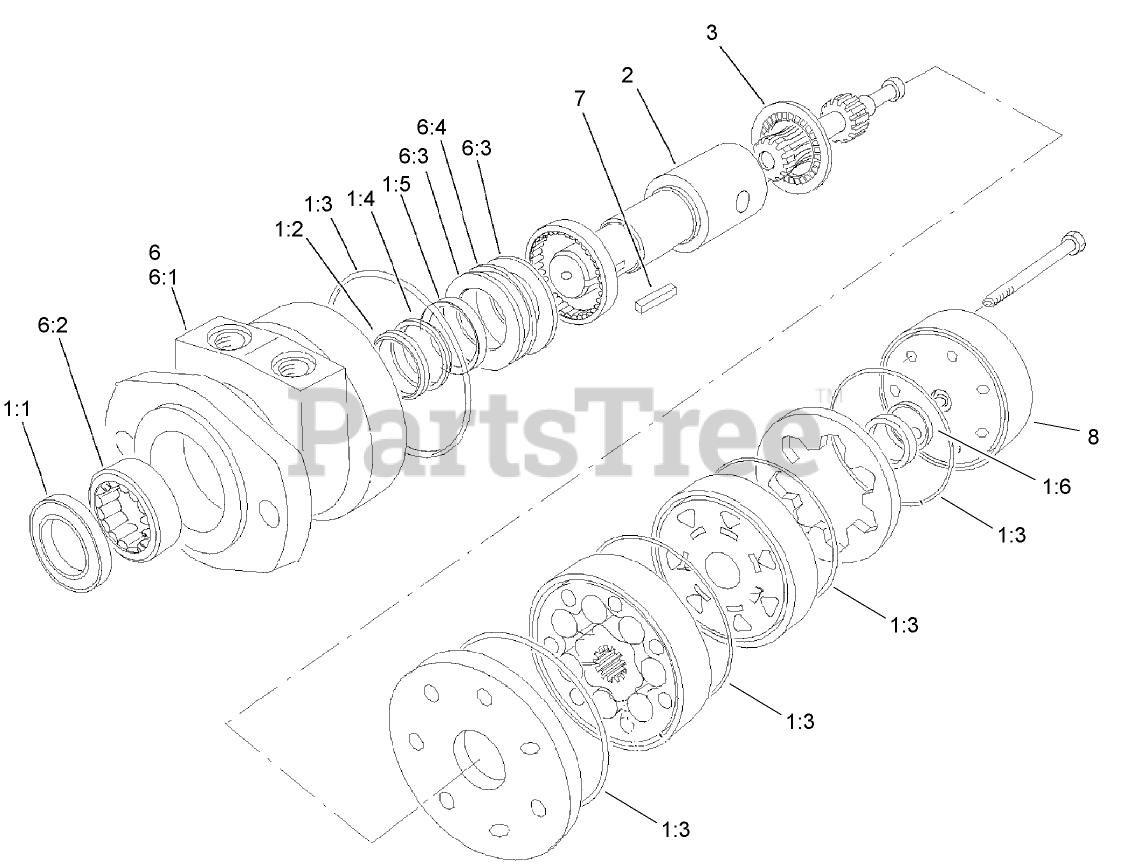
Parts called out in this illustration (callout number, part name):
1	SEAL KIT
1:1	SEAL-DIRT AND WATER (Not serviced separately)
1:2	Washer-Backup (Not serviced separately)
1:3	Seal-Ring (Not serviced separately)
1:4	Washer-Backup (Not serviced separately)
1:5	Seal-Inner (Not serviced separately)
1:6	Seal-Commutator (Not serviced separately)
2	COUPLING SHAFT
3	BEARING-THRUST
6	HOUSING ASM
6:1	Housing (Not serviced separately)
6:2	Bearing (Not serviced separately)
6:3	Washer-Thrust (Not serviced separately)
6:4	Bearing-Thrust (Not serviced separately)
7	KEY-SQUARE
8	END COVER ASM
